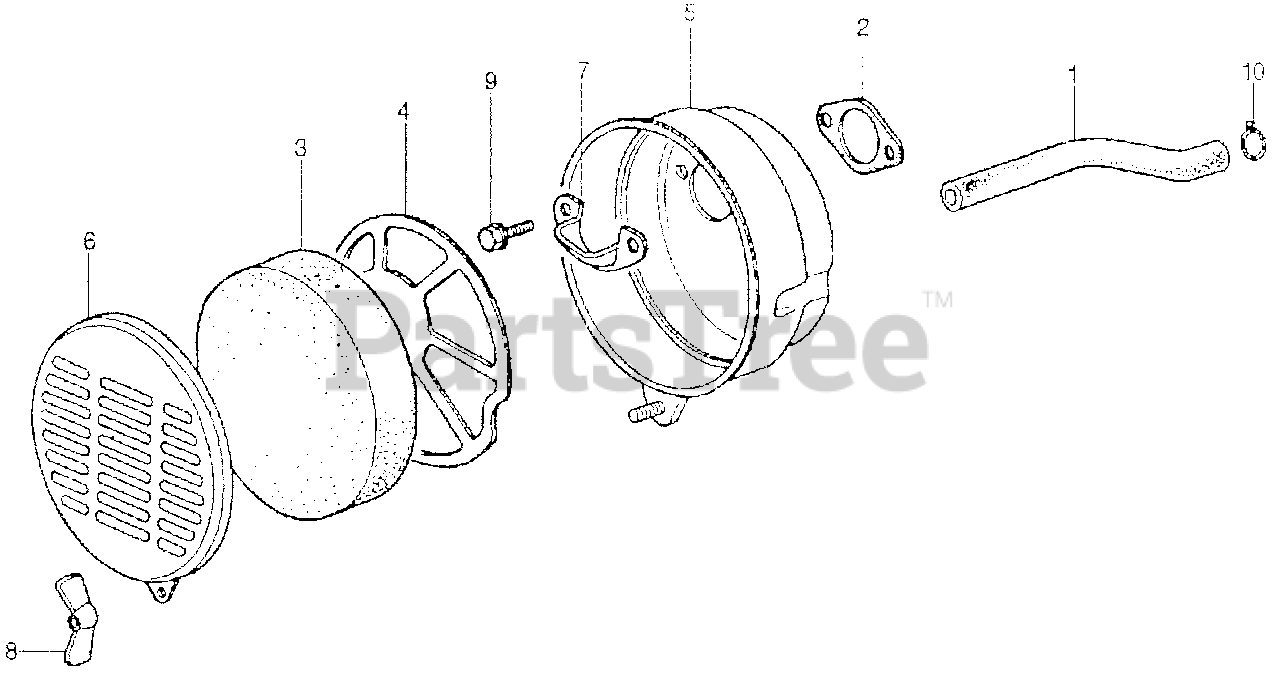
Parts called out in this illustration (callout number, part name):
1	TUBE, BREATHER
2	GASKET, AIR CLEANER (NOT AVAILABLE)
3	ELEMENT, AIR CLEANER
4	GRID, CLEANER
5	HOUSING, AIR CLEANER *R8* (BRIGHT RED) (NOT AVAILABLE)
6	COVER, AIR CLEANER *R8* (BRIGHT RED) (NOT AVAILABLE)
7	PLATE, BAFFLE (NOT AVAILABLE)
8	WINGNUT, TOOL BOX SETTING
9	BOLT, HEX. (6X12)
9	BOLT, FLANGE (6X12)
10	CLIP, TUBE (B12.5)
